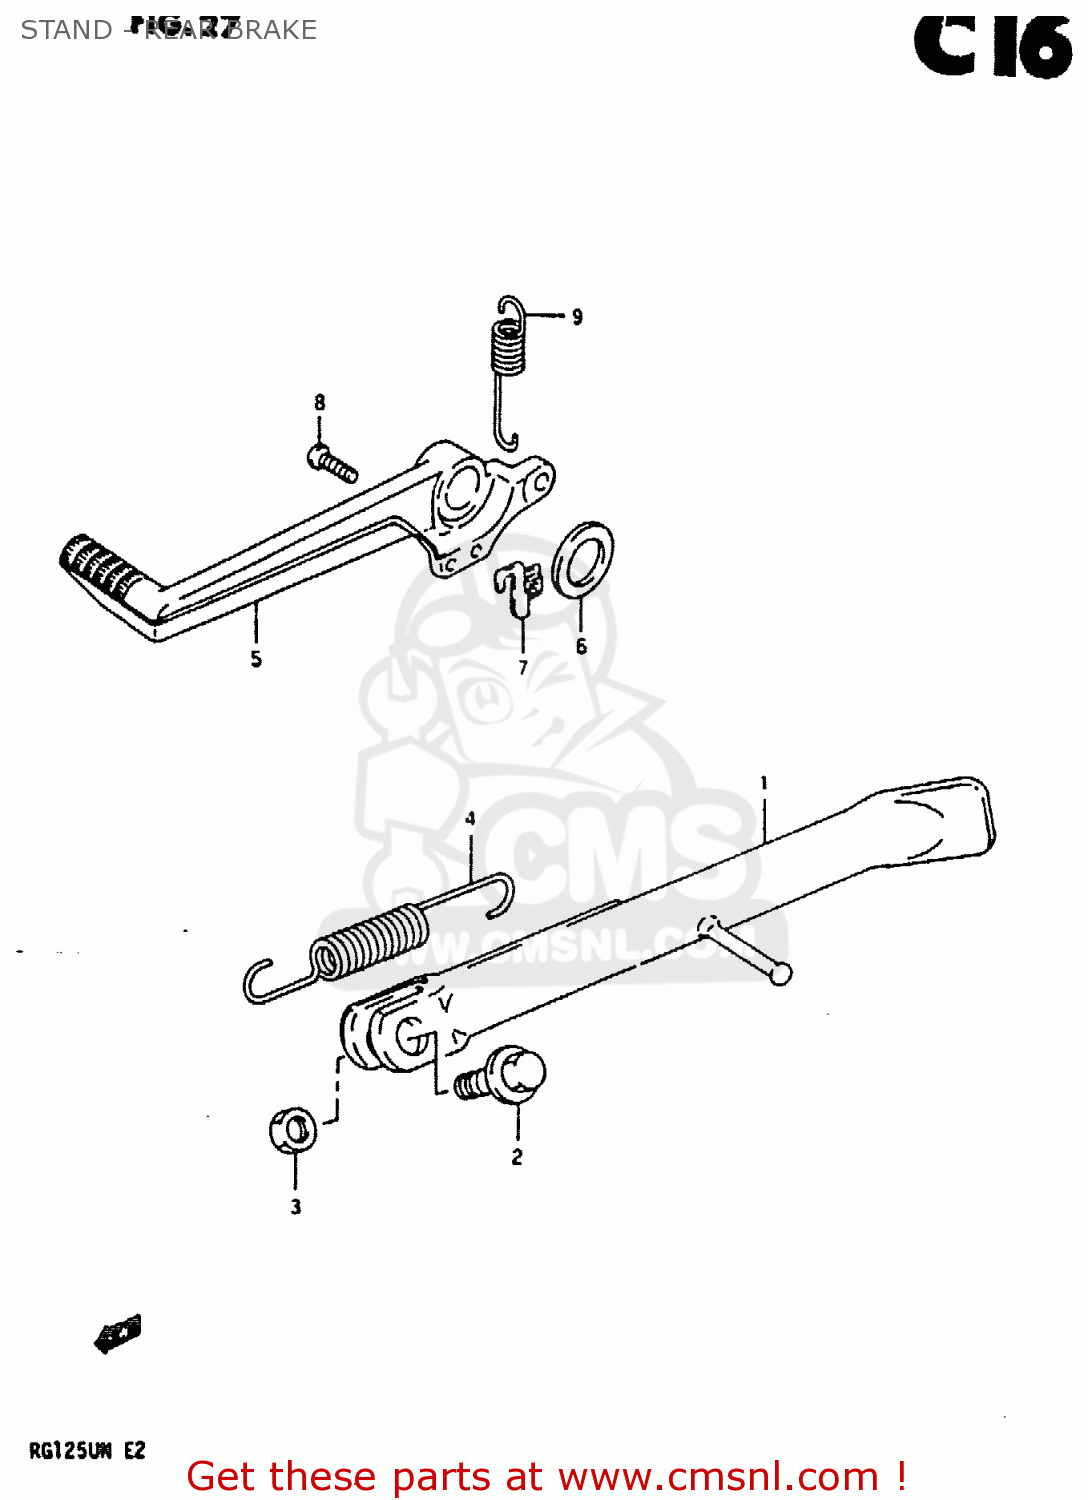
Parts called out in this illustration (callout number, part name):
1	STAND,PROP
2	BOLT(10X30)
3	NUT
4	SPRING
5	PEDAL, BRAKE
6	WASHER(18.2X27X1)
7	BRACKET, SPRING
8	SCREW
9	SPRING
